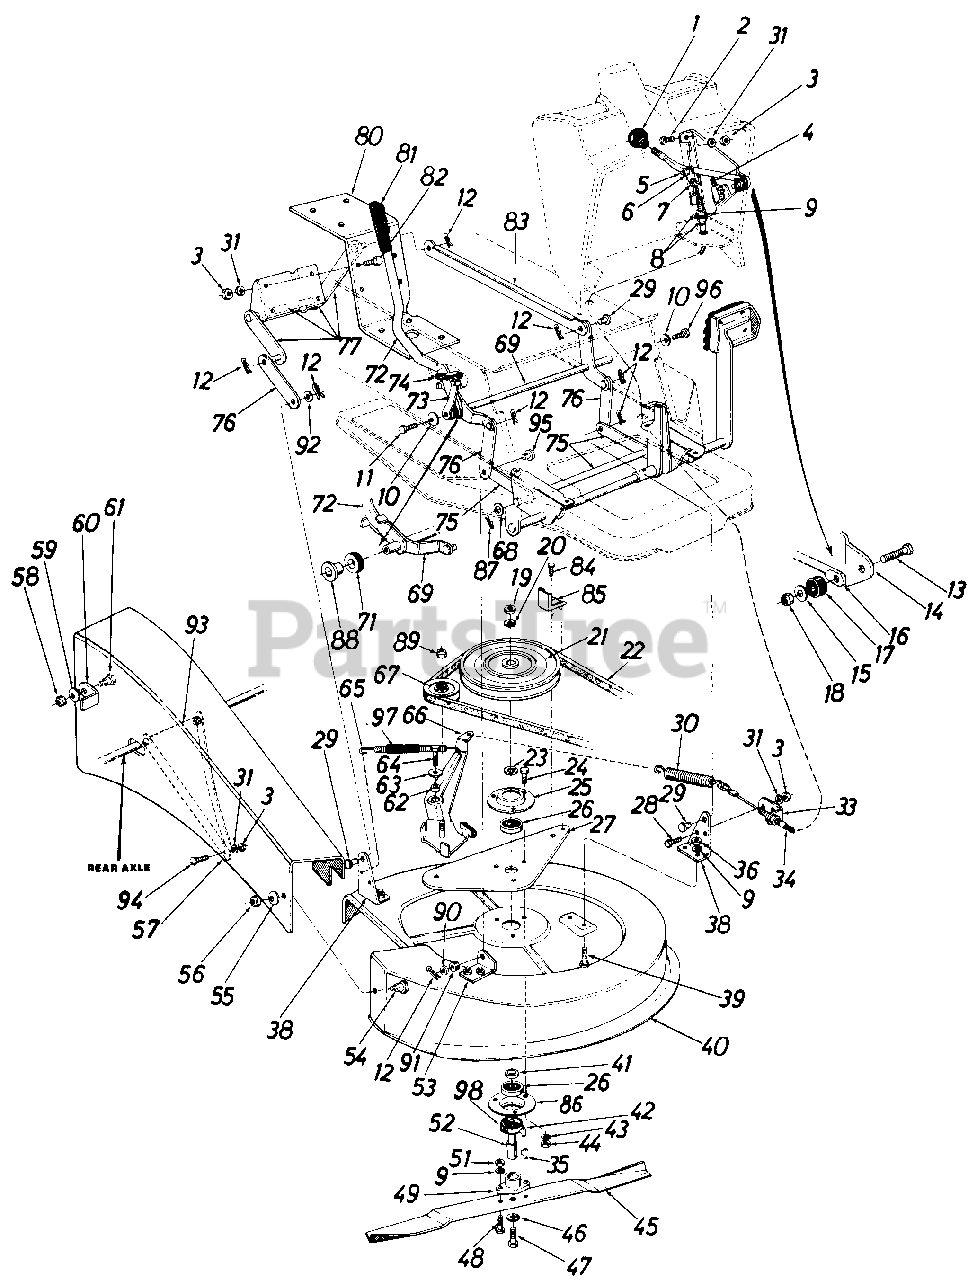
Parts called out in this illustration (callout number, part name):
1	Ball Knob
2	Truss Mach. Scr. 1/4-20 x .50" Lg.
3	Hex Nut 1/4-20 Thd.
4	Safety Switch
5	Weld Pin .250 Dia. x .62" Lg.
6	Push Cap .250 Dia.
7	Clevis
8	Hex Jam Nut 5/16-24 Thd.
9	L-Wash. 5/16" Scr.*
10	Bell-Wash. .400 I.D. x 1.110 O.D.
11	Hex Wash. Hd. Self-Tap Scr. 3/8-1 6 x 125" Lg.
12	Internal Cot-Pin 1/2" Dia.
13	Hex Scr. 1/4-20 x 1.25" Lg.
14	Deck Clutch Control Brkt.
15	Fl-Wash. .280 I.D. x .750 O.D. x .063
16	Blade Clutch Lever
17	Rubber Washer
18	Hex Cent. L-Nut 1/4-20 Thd.
19	Hex Nut 5/8-11 Thd.
20	L-Wash. 5/8" Scr.
21	Deck Pulley
22	"V"-Belt "A" or 1/2" x 54" Lg.
23	Spacer
24	Hex Sems Scr. 5/16-18 x 1.00" Lg.*
25	Bearing Housing
26	Ball Brg. .787 I.D. x 1.850 O.D.
27	Deck Belt Guard Plate
28	Hex Sems Scr. 1/4-20 x .75" Lg.*
29	Lift Brkt. Pin Special
30	Extension Spring .88 O.D. x 4.0" Lg.
31	L-Wash. 1/4" Scr.*
33	Cable Bracket
34	Clutch Control Cable 26.88" Lg.
35	#6 Hi-Pro Key 5/32 x 518" Dia.
36	Hex Nut 5/16-18 Thd.
38	Deck Bracket
39	Carriage Bolt 5/16-18 x .75"
42	#61 Hi-Pro Key 3/16 x 5/8" Dia.
43	L-Wash. 5/16" Scr.
44	Hex Nut 5/16-18 Thd.
45	26" Blade
46	L-Wash. 3/8" Scr. H.D.
47	Hex Scr. 3/8-24 x 1.50" Lg. H.T.
48	Hex Scr. 5/16-24 x 1.00" Lg. H.T.-Special
49	Blade Adapter Kit
51	Hex Nut 5/16-24 Thd.
52	Blade Spindle
53	Deck Bracket
54	Shld. Scr. .500 Dia. x .170 Lg.
55	Fl-Wash. .385 I.D. x .88 O.D.
56	Hex Cent. L-Nut 3/8-16 Thd.
57	Chute Ass'y.
58	Hex Ins. L-Nut 5/16-18 Thd.
59	Bell. Wash. .345 I.D. x .88 O.D.
60	Chute Pivot Brkt.
61	Shld. Scr. .437 I.D. x .180" Lg.
62	Spacer .315 I.D. x .75 O.D. x .370 Lg.
63	Fl-Wash. .344 I.D. x 1.12 O.D. x .12
64	Hex Scr. 5/16-18 x 1.00" Lg.
65	Extension Spring
66	Deck Idler Brkt. Ass'y.
67	V-Idler Pulley
68	Fl-Wash. .630 I.D. x .930 O.D. x .060
69	Lift Handle Shaft Ass'y.
71	Rubber Wash.
72	Lift Handle
73	Lift Handle Stop
74	Height Adj. Knob
75	Lift Arm Shaft Ass'y.
76	Deck Link
77	Lift Pivot Brkt. Ass'y.
80	Seat Support Ass'y.
81	G ri p
82	Hex Sems Scr. 1/4-20 x 1.00" Lg.*
83	Connecting Link
84	Hex Wash. Hd. Self-Tap Scr. 5/16-24 x .75" Lg.
85	Belt Keeper Ass'y.
86	Open Bearing Hsg.
87	Cotter Pin 3/32" Dia. x .75"
88	Flange Brg. .62 I.D. x .87 O.D. x .63" Lg.
89	Hex Ins. L-Nut 3/8-24 Thd.
90	Fl-Wash. .530 I.D x .940 O.D. x .050
91	Rubber Wash. .531 I.D. x 1.00 O.D. x .120
92	Fl-Wash. .531 I.D. x .93 O.D. x .090
93	Chute Baffle
94	Carriage Bolt 1/4-20 x .50"
95	Clevis Pin .500
96	Self-Tap Scr. 3/16-16 x 1.0" Lg.
97	Shrlnk Tube
98	Bearing Shield
